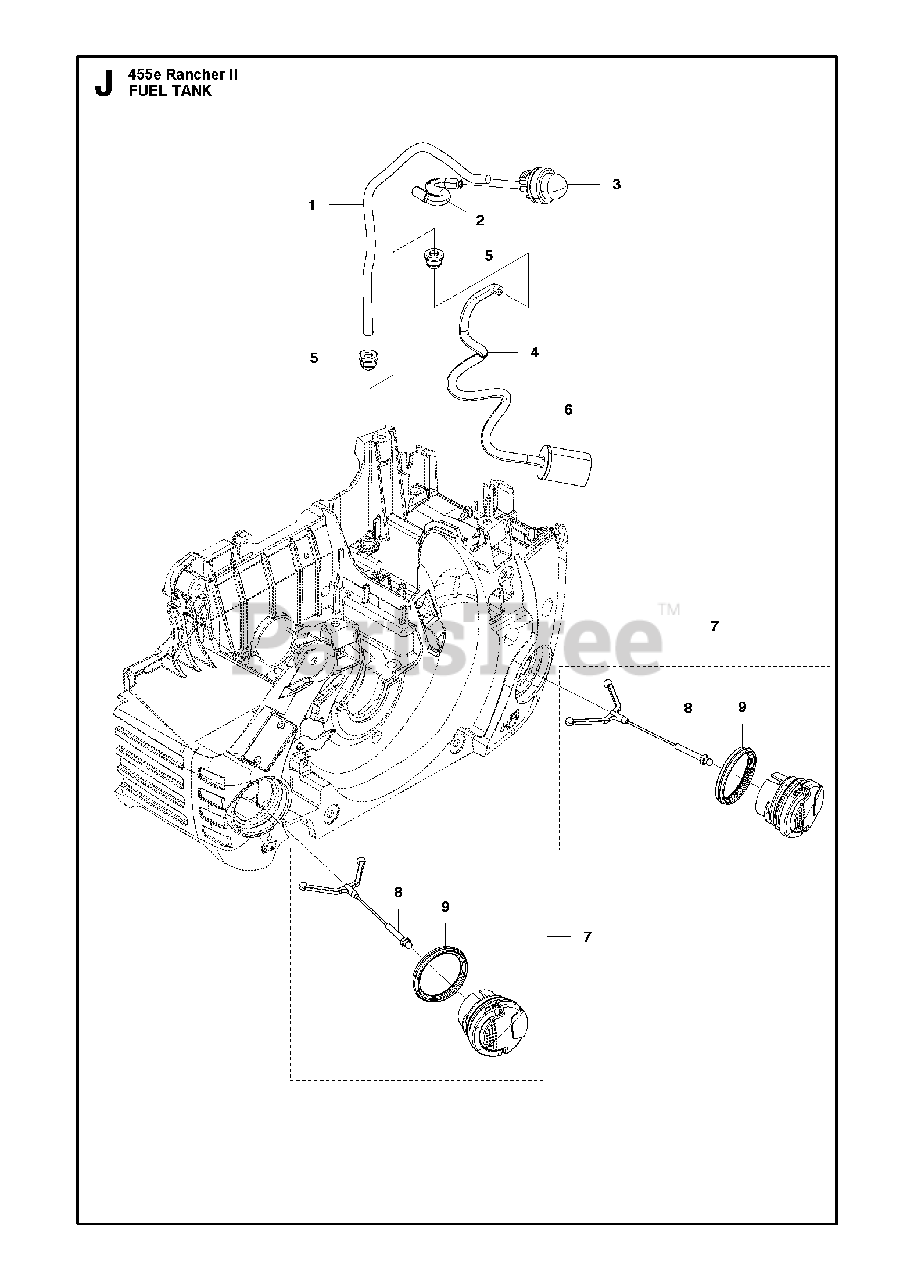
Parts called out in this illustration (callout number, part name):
3	AIR PURGE BUBBLE
4	FUEL HOSE
5	FUEL TANK BUSHING
6	FUEL FILTER
7	TANK CAP ASSY
8	HOLDER
9	SEALING
